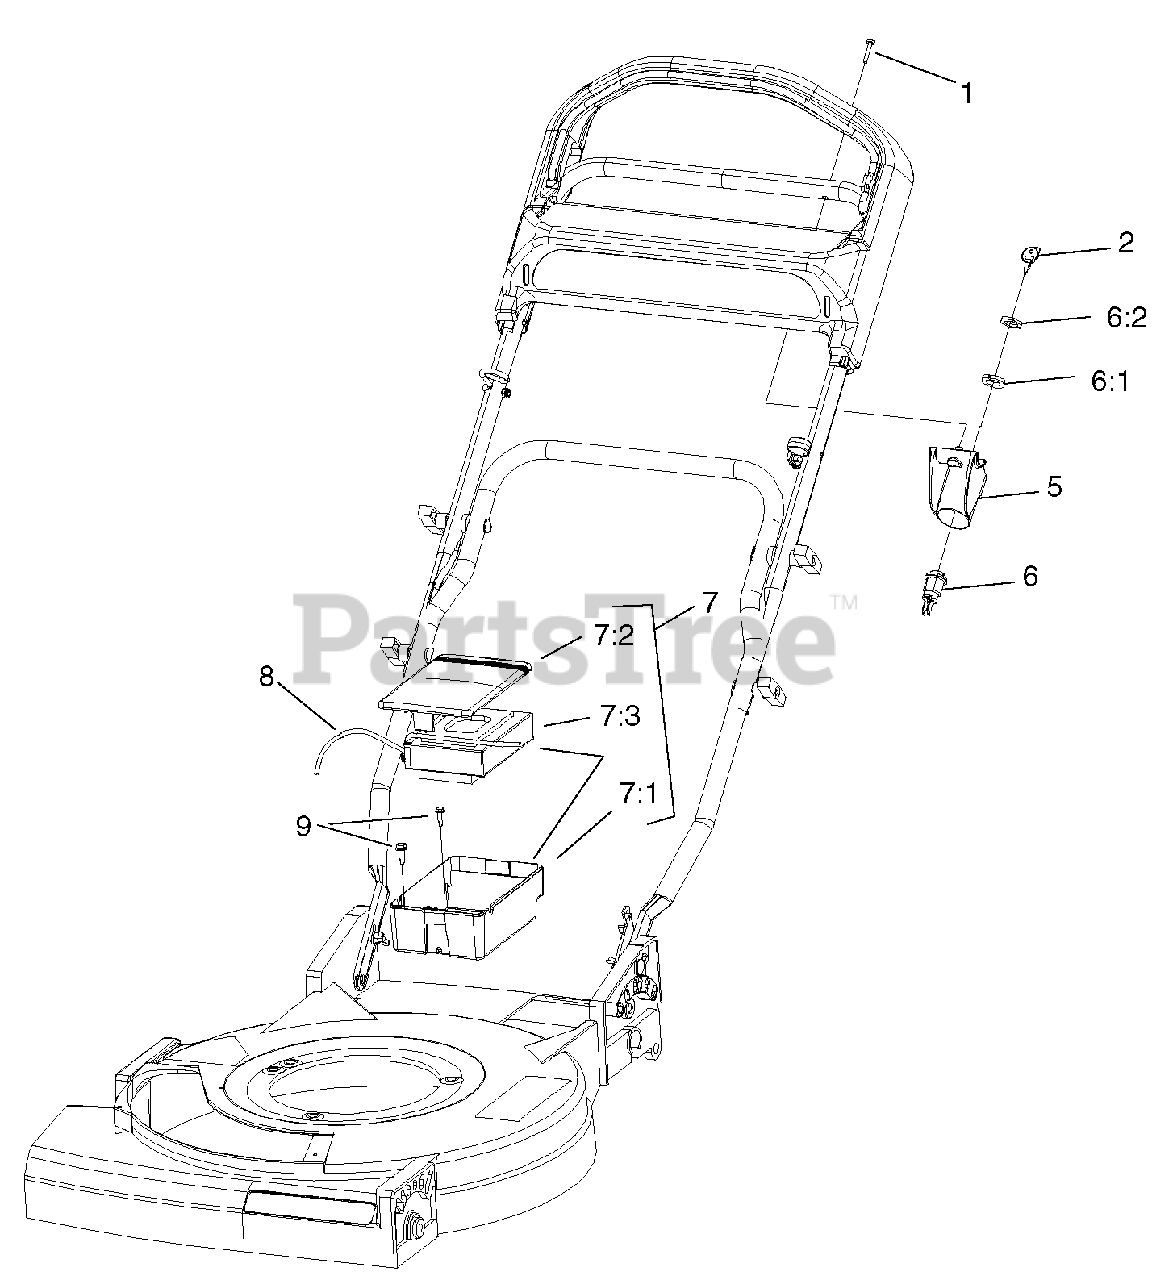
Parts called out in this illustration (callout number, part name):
1	SCREW-PLASTITE
2	KEY - IGNITION
5	SWITCH-HOLDER
6	SWITCH-STARTER
6:1	WASHER-LOCK, INTERNAL
7	BATTERY ASM-PANASONIC
7:1	BOX-BATTERY
7:2	COVER-BATTERY
7:3	BATTERY-PANASONIC, 12V
8	HARNESS-WIRE
9	SCREW-TEK
